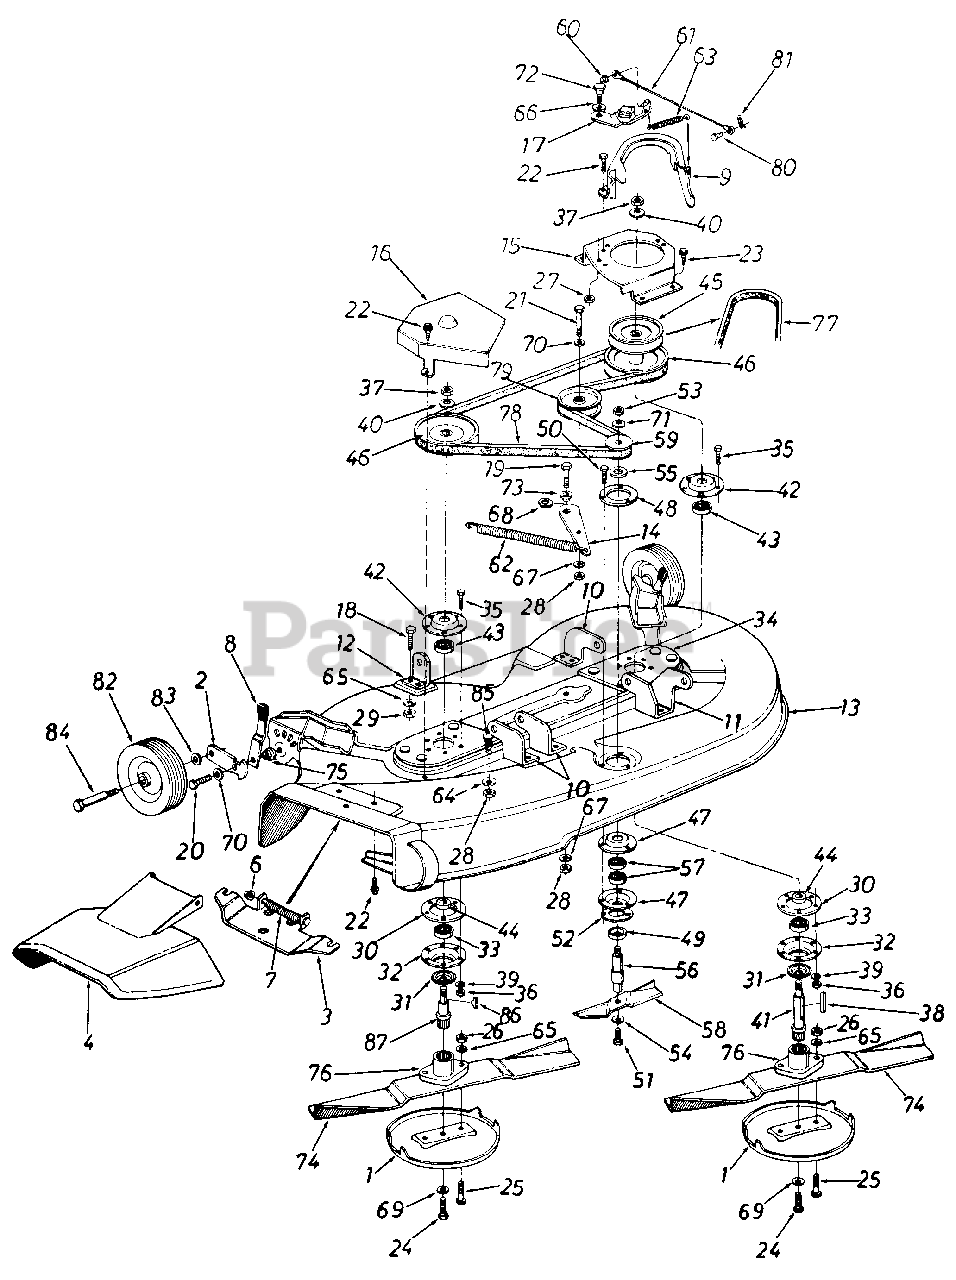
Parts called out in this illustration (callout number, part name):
1	Anti-Scalp Plate
2	Bar-Wheel Pivot
3	Adapter Plate
4	Chute Cover Ass'y.
4	Hinge Pin
6	Cap Speed Nut 1/4" Rod
7	Torsion Spring
8	Spring Lever Ass'y.
9	Belt Guard
12	Deck Hanger Bracket 1.91
13	44" Deck Ass'y
14	Idler Bracket
15	Pulley Cover L.H.
18	Hex Bolt 5/16-18 x .75" Lg.*
19	Hex Bolt 3/8-24 x 1.00" Lg.*
20	Hex Bolt 3/8-24 x 1.25" Lg.*
21	Hex Bolt 3/8-24 x 1.50" Lg.*
22	Hex Wash. S-Tapp Scr. 1/4-20 x .50
23	Hex Wash. Hd. Tapp Scr. 5/16-18 x .75" Lg.
24	Hex Cent. L-Bolt 3/8-24 x .88" Lg.
25	Hex Bolt Special 5/16-24 x 1.0" Lg.
26	Hex Nut 5/16-24 Thd.*
27	Hex Cent. L-Nut 5/16-18 Thd.
28	Hex Nut 3/8-24 Thd.*
29	Hex Nut 5/16-18 Thd.*
30	Reinforcement Plate
31	Bearing Shield
32	Open Brg. Housing 1.85" I.D.
33	Ball Brg. .787" I.D. x 1.85" O.D. x .551
34	Spindle Mounting Plate Ass'y
35	Hex Bolt Special 5/16-24 x 1.0" Lg.
36	Hex Nut 5/16-24 Thd.*
37	Hex Jam N ut 5/8-18 Thd.*
38	Sq. Key 3/16" x 3/16 x 2.25" Lg.
39	L-Wash. 5/16" I.D.*
40	Bell-Wash. .630" I.D. x 1.25" O.D.
41	44" Deck Blade Spindle
42	Bearing Housing 1.85" I.D.
43	Ball Brg. .787" I.D. x 1.85" O.D. x .551
44	Spacer 1.0" O.D. x .790" I.D.
45	5/8 "V"-Pulley .79" I.D. x 5.75" O.D.
46	V-Pulley .79" I.D. x 6.50" O.D.
47	1-3/8" I.D. Bearing Housing
48	Reinforcement Plate
49	Bearing Shield
50	Hex Sems Scr. 1/4-28 x .625" Lg.
51	Hex Cent. L-Bolt 3/8-24 x .88" Lg.
52	Ring Nut 1/4-28 Thd.
53	Hex Jam Nut 1/2-20 Thd.*
54	Bell-Wash. .400" I.D. x .88" O.D.
55	Fl-Wash. .635" I.D. x 1.04" O.D.
56	6.5" Blade Spindle
57	Ball Brg. .62" I.D. x 1.38" O.D. x .44
58	6.50" Blade
59	1/2" "V"-Pulley Half .625" I.D. x 2.25" O.D.
60	Cap Speed Nut 1/4" Rod
61	Brake Cable 11.75" Lg.
62	Extension Spring .73" O.D. x 4.31 " Lg.
63	Ext. Spring .50" x 2.5" Lg.
64	Bell-Wash. .400" I.D. x .88" O.D.
65	L-Wash. 5/16" I.D.*
66	Spring Wash. .445" I.D. x .75" O.D.
67	L-Wash. 3/8" I.D.*
68	Spring Wash. .625" I.D. x .885" O.D.
69	L-Wash. 3/8" I.D (Heavy Duty)
70	Bell-Wash. .400" I.D. x 1.13" O.D.
71	Bell-Wash. .505" I.D. x 1.00" O.D.
72	Shld. Bolt .437" Dia. x .180
73	Shld. Spacer .625" I.D.
74	21" Blade
75	Shld. Spacer
76	Blade Adapter
77	V-Belt 1/2" x 52.0" Lg.
78	V-Belt 1/2" x 74.0" Lg. (Drive Belt)
79	Fl-ldler w/ Flanges 3.50" O.D.
80	Clevis Pin 1/4" Dia. x .53" Lg.
81	Intern. Cotter Pin 5/16" Dia.
82	Deck Wheel 6.0" x 1.38
83	Bell-Wash. .400" I.D. x .88" O.D.
84	Shld. Bolt 3/8-16 x 1.41
85	Rib Neck Bolt
86	Sq. Key 3/16" x 3/16" x .75" Lg.
87	44" Deck Blade Spindle
